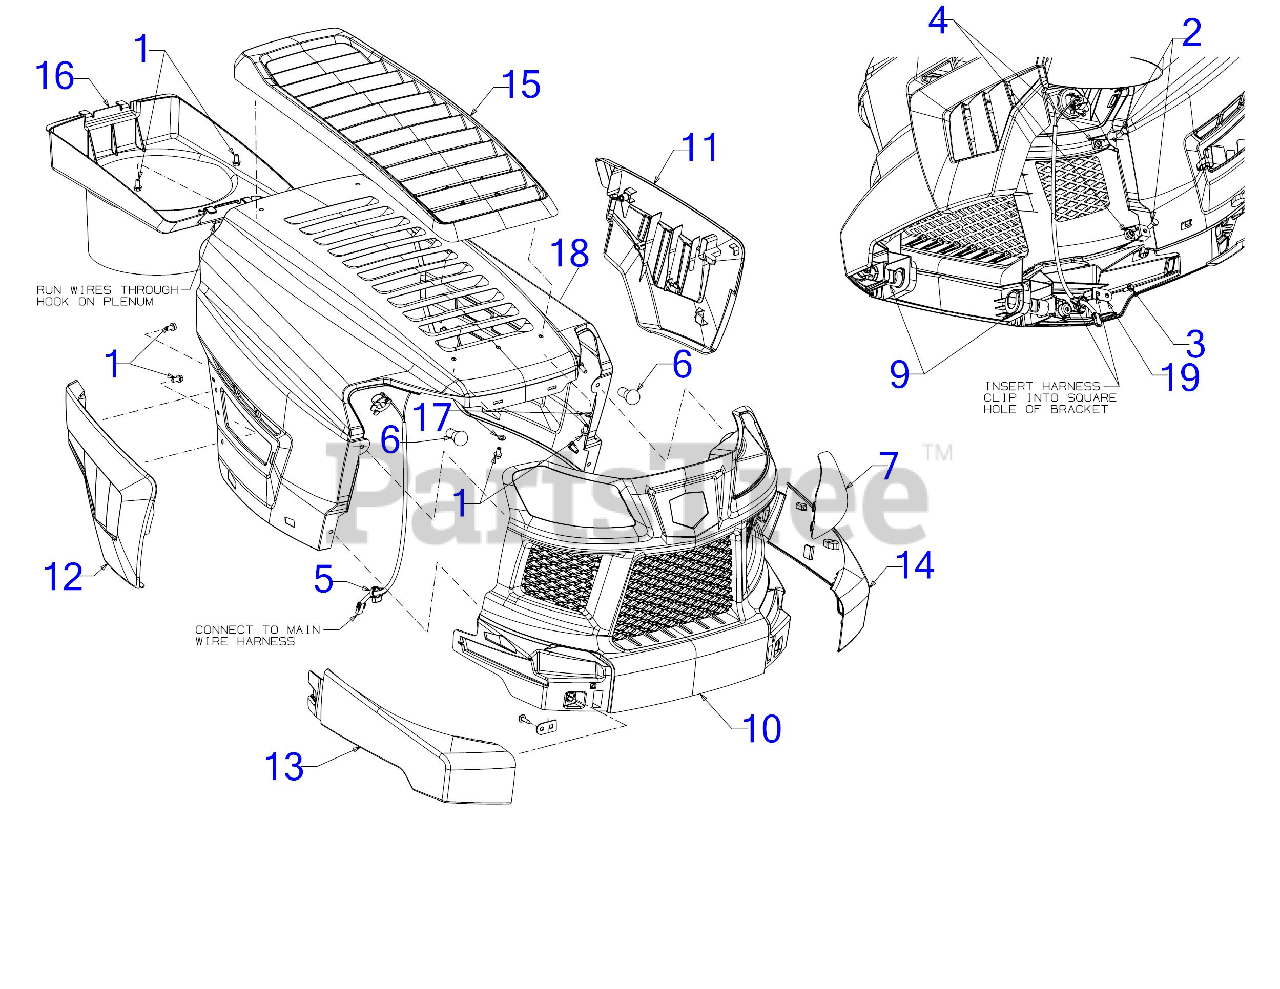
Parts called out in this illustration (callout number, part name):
1	HEX SCREW 1/4-15 x .50
2	SCREW 1/4-20 x .62 SPEC GR5
3	SCREW 1/4-10 x .750
4	SQUARE NUT 1/4-20
5	HEADLIGHT HARNESS
6	MINIATUURE BULB 12V
7	GRILLE LENS (LH)
9	HOOD PIVOT PIN
10	GRILLE (CRAFTSMAN)
11	HOOD SIDE COVER (LH)
12	HOOD SIDE COVER (RH)
13	GRILLE PANEL- (RH)
14	GRILLE PANEL- (LH)
15	HOOD SCOOP
16	HOOD PLENUM
17	FLAT WASHER .281 x .50 x .063
19	HARNESS CLIP BRACKET
